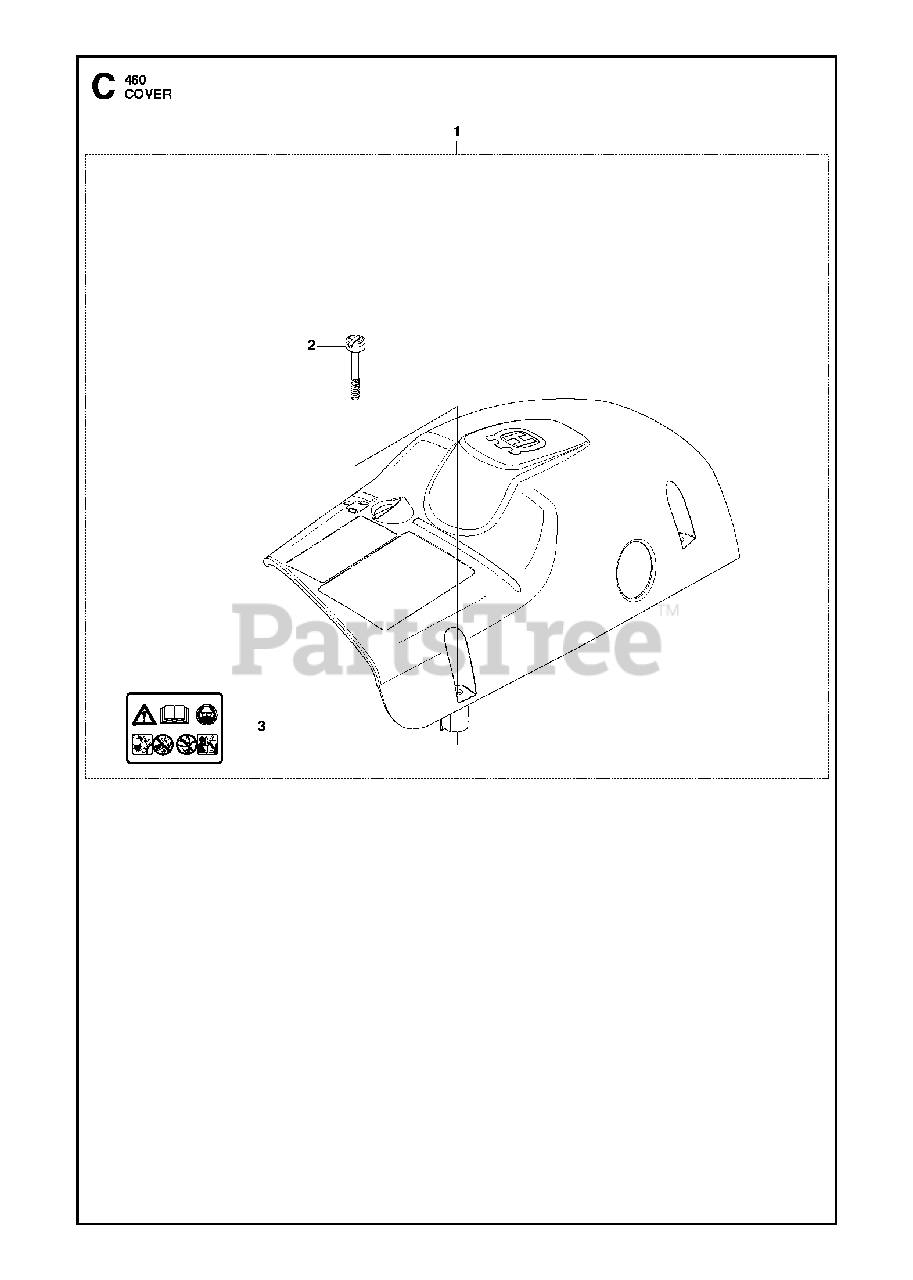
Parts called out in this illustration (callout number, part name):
1	CYLINDER COVER
2	SCREW
3	DECAL
